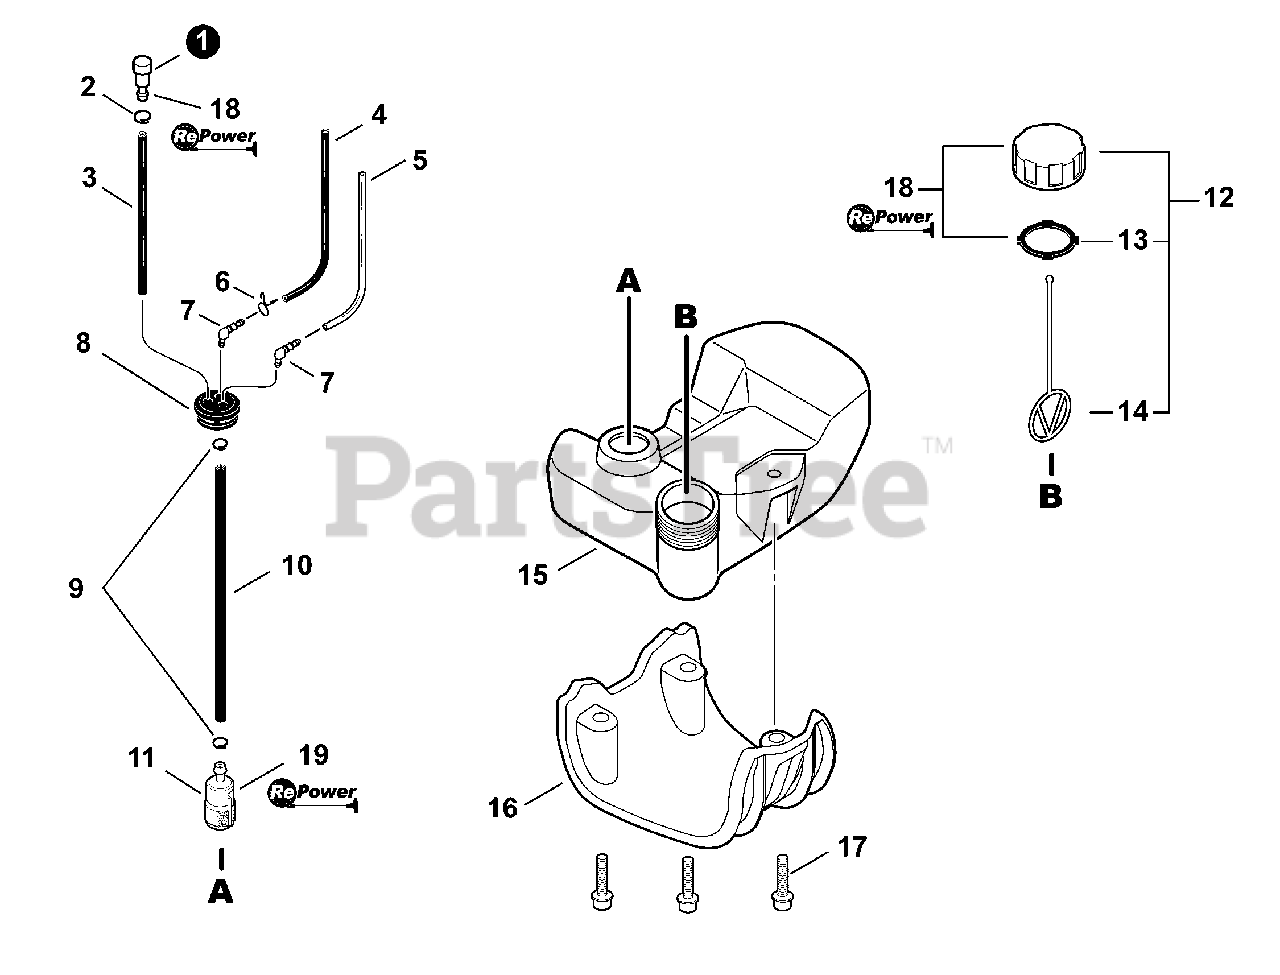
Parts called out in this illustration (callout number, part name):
1	VENT ASSY
2	CLIP Ø6.5 MM
3	PIPE 3×6×115 BLACK
4	PIPE, FUEL 3×5×87 BLACK
5	PIPE, FUEL 3×6×80 CLEAR
6	CLIP, SPRING Ø5.2
7	CONNECTOR, PIPE
8	GROMMET, FUEL
9	CLIP Ø6
10	PIPE, FUEL - 3×5×125 - BLACK
11	FILTER, FUEL
12	CAP ASSY, FUEL
13	GASKET, FUEL CAP
14	CONNECTOR, CAP L= 100 MM
15	TANK, FUEL
16	GUARD, FUEL TANK
17	BOLT 5×20
18	CAP/VENT KIT - REPOWER
19	TUNE-UP KIT - REPOWER
